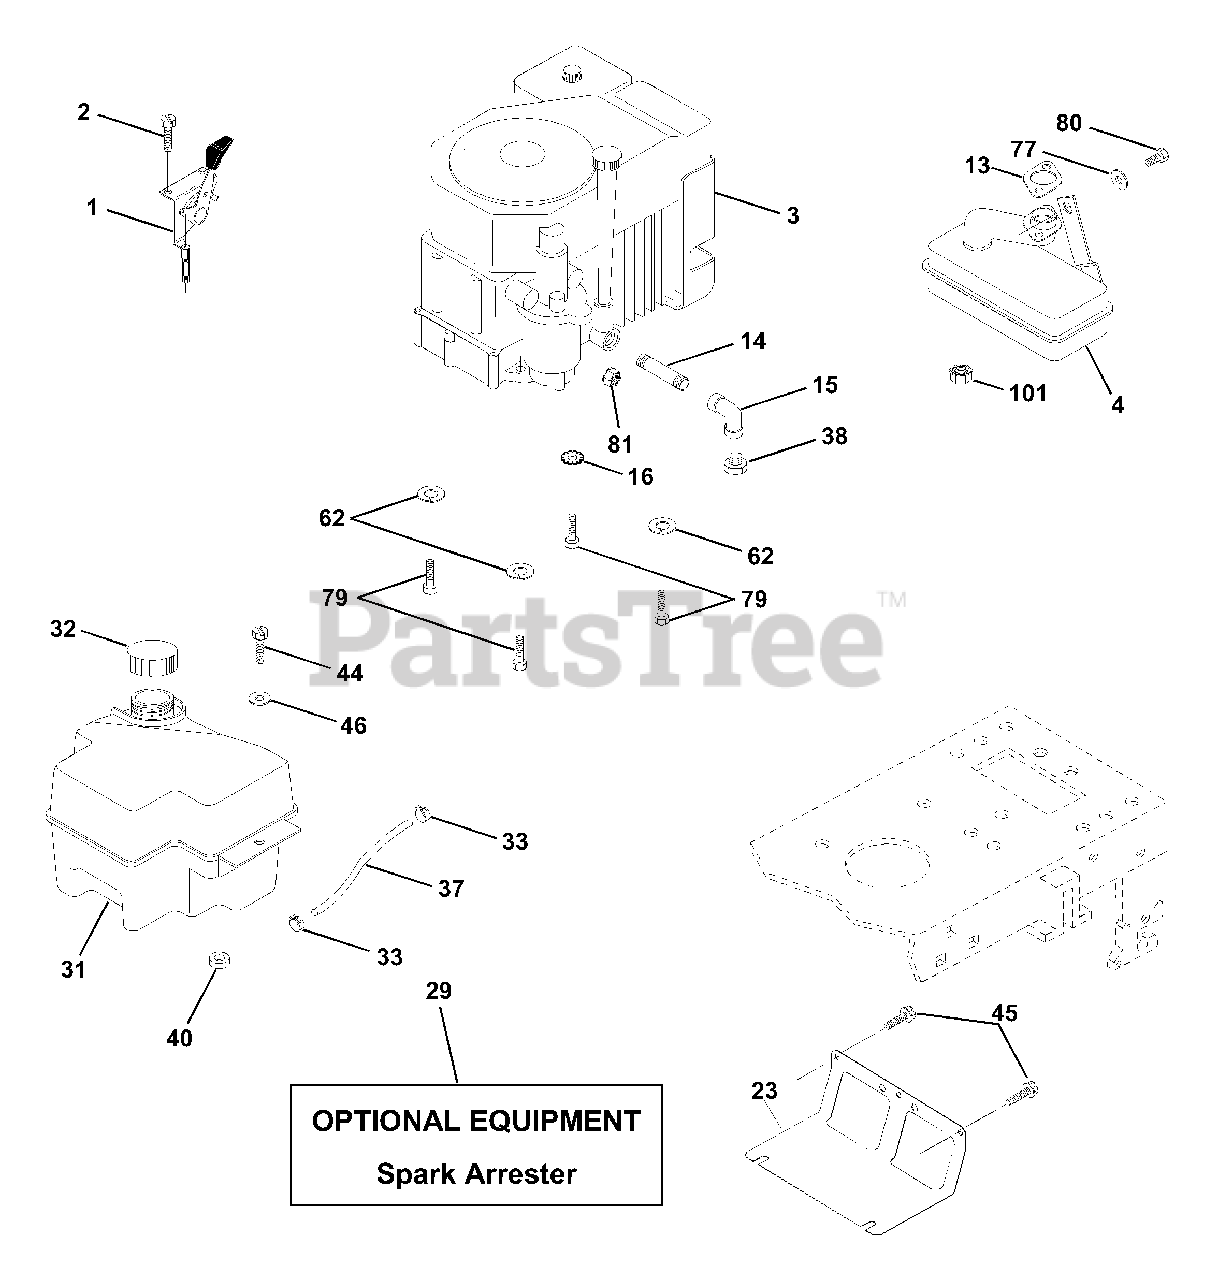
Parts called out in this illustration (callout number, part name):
1	Control Th/ch Flag
2	Screw Hex Thd Cut 1/4-20x5/8 T
4	Muffler
13	Gasket Muffler
14	Nipple Pipe 3/8 NPT x 3-1/2
15	Elbow Std 90 Degree 3/8-18 Npt
16	Washer Lock Ext Tooth 5/16
23	Shield Brn/Dbr Guard
29	Arrestor Spark
31	Tank Fuel Front 2 00
32	Cap Fuel
33	Clamp Hose Black
37	Line Fuel 20"
38	Plug Oil Drain
40	Bushing Snap Nyl Blk Fuel Line
44	Screw Hex wsh Thdrol 1/4-20x3/4
45	Screw Hex Wsh Thdrol 3/8-16 x 3/4
46	Washer 9/32 X 7/8 X 16 Ga
62	Washer Lock Hvy Hlcl Spr 5/16
77	Washer 5/16 x 3/4 x 16 Ga
80	Bolt Hex Hd 5/16-18 Unc x 1/2
81	Nut Keps Hex 1/4-20 Unc
101	Nut Flange M8-1.25 Non-Lk
